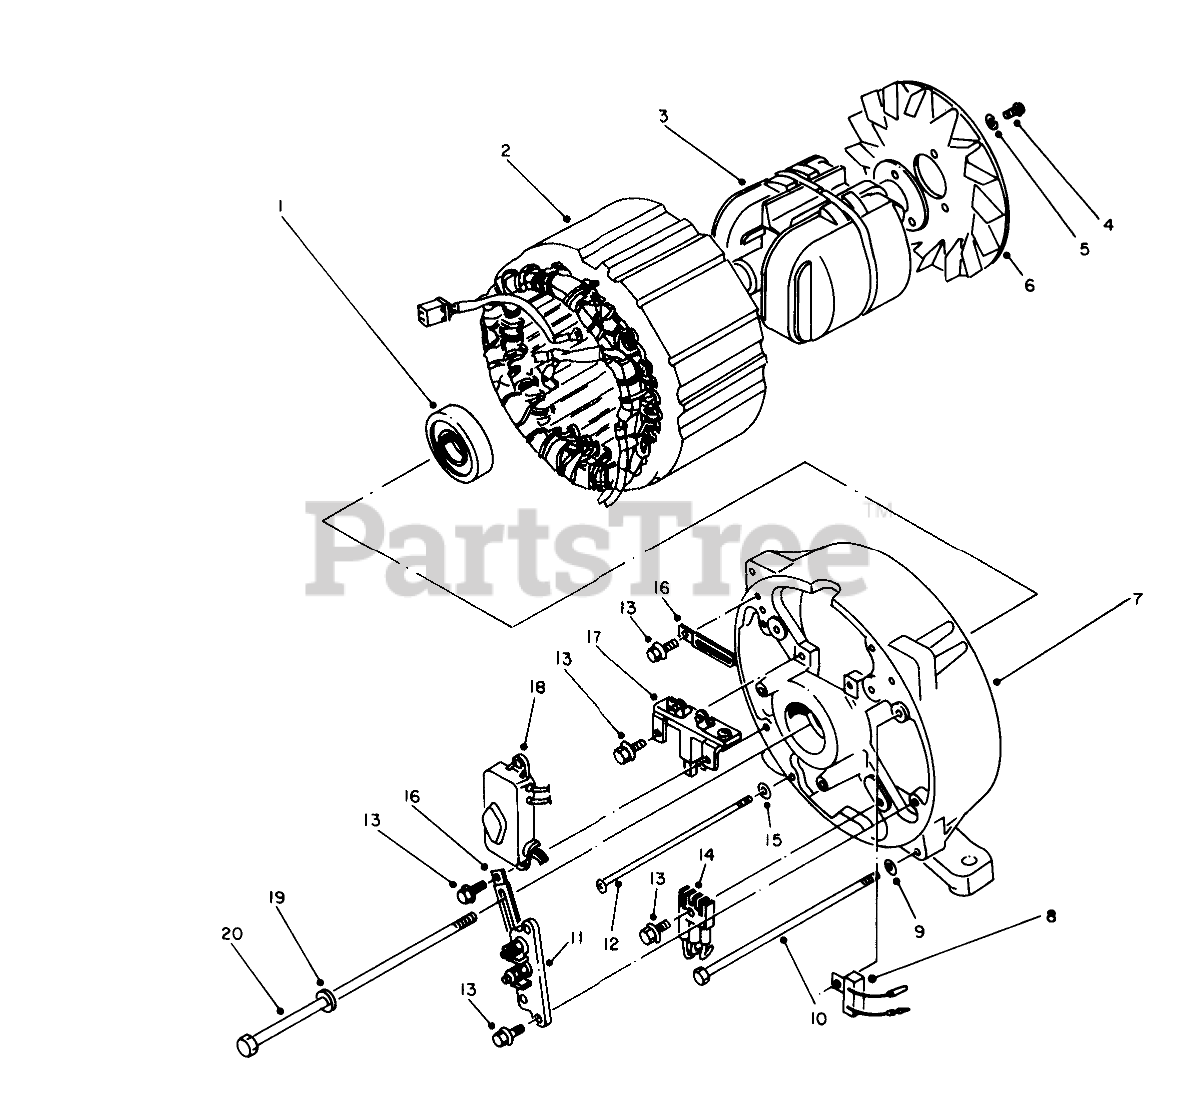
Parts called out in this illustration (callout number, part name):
1	Bearing
2	Stator
3	Rotor
4	SCREW
5	Washer
7	Bracket-Rear
8	Register
9	Washer
10	BOLT (6X171)
11	Terminal
12	Screw
13	Bolt
14	Diode
15	WASHER
16	Clamp
17	Holder-Brush
18	Regulator-Voltage
19	Washer
